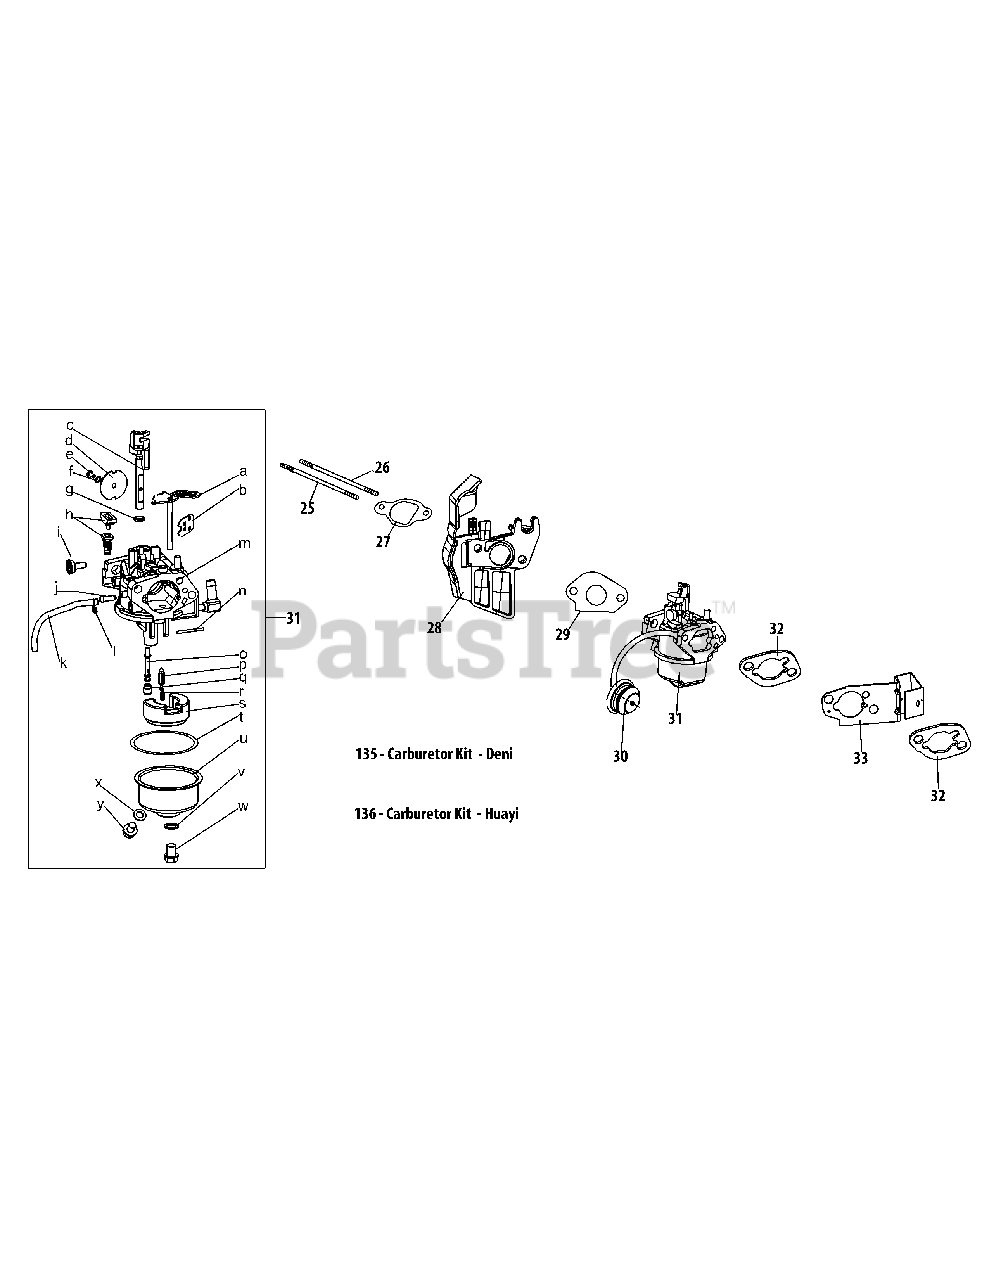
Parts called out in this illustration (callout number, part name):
25	Stud M6×117
26	Stud M6×105
27	Carburetor Insulator Gasket
28	Carburetor Insulator
29	Carburetor Gasket
30	Primer Assembly
30	Primer Bulb
31	Carburetor Assembly: - Huayi
31	Carburetor Assembly: - Deni
32	Carburetor Gasket Plate
33	Choke Control Bracket
135	Carburetor Kit - Deni
136	Carburetor Kit - Huayi
